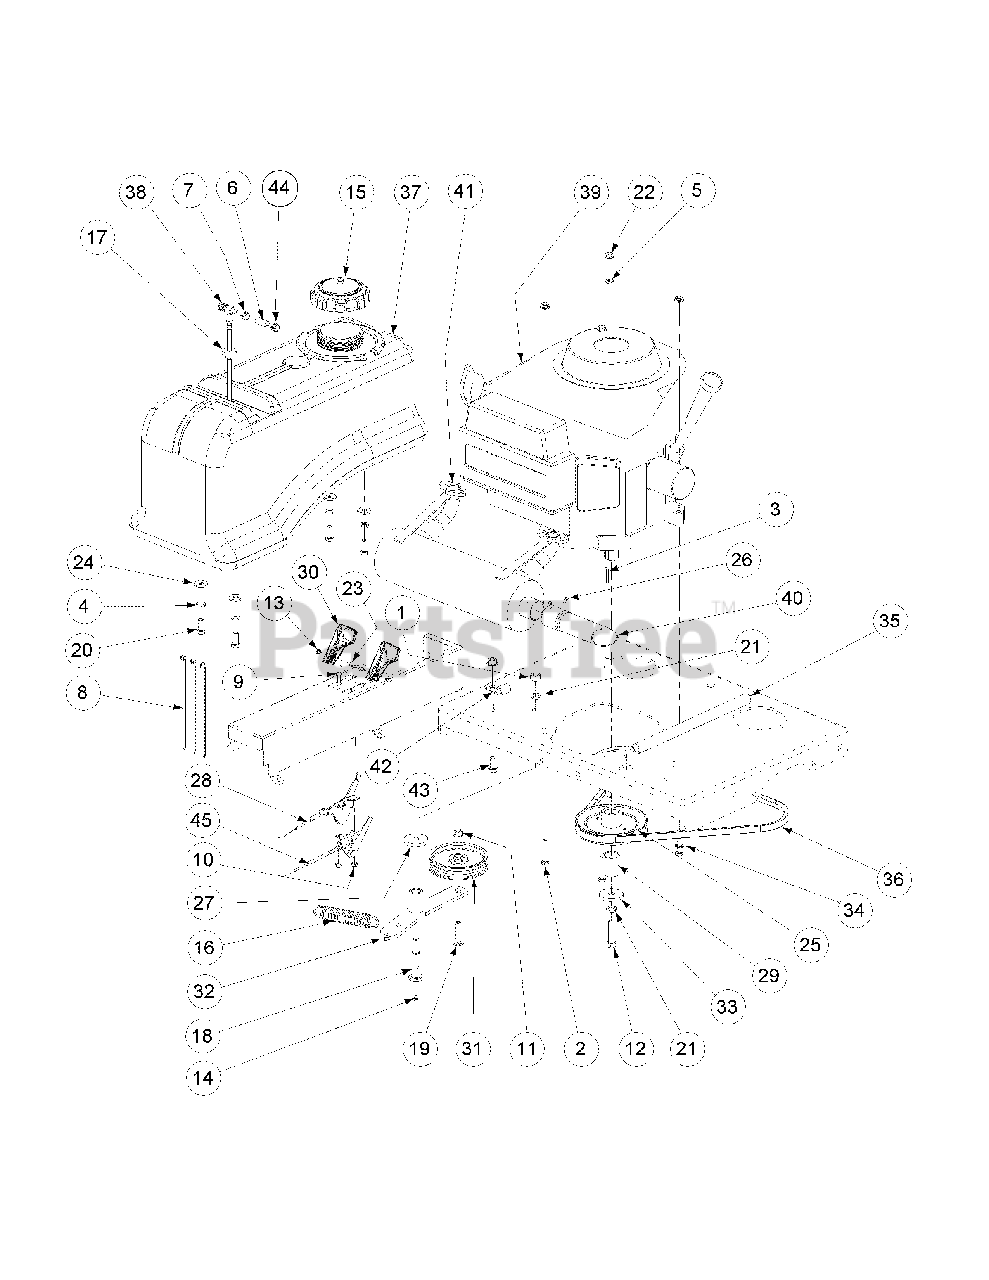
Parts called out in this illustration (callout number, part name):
1	Nut Hex, 7/16-14
2	HHCS, 5/16-18, 1-3/4
3	Key, 1/4 x 1/4 x 1.125
4	Lock Washer, 3/8
5	Flat Washer, 5/16
6	Hose, 1/4" Fuel Line
7	Clamp, Union
8	Cable Tie
9	Screw, Machine, 10-32 x 3/4
10	Nut, Lock, Nylon Insert, #10-32
11	Nut, Hex, Flange Lock, 3/8-16
12	Capscrew, 7/16-20 x 1.75
13	Nut, Washer, With Star, 8-32
14	Fitting, Grease, 1/4-28 x 3/16
15	Fuel Cap, 3.5
16	Spring, Extension, 1.0 OD x 5.0"
17	Fuel Tank Grommet
18	Shoulder Screw, 7/16-14
19	Bolt, Carriage, 3/8-16 x 1.75
20	Hex, Cap Screw, 3/8-16, .88
21	Washer, Lock, 7/16
22	Nut Lock, Hex Flange 5/16-18
23	Machine Screw, 8-32, .375
24	Flat Washer, .406 ID, 1.0 OD, .105
25	Pulley, Transmission Drive
26	Screw, 8-32 x 0.375
27	Washer, Flat, 7/16 ID x 1.75 OD
28	Cable, Control 39.0 Throttle
29	Spacer, 1.015 ID x 1.25 OD x 1.50
30	Knob, Throttle Control
31	Flat Pulley with Flanges
32	Engine Idler Arm Assembly Includes:
32	Bearing
33	Flat Washer, 7/16 ID x 1.75 OD
34	External Tooth Washer, 3/8
35	Oil Drain Extension Hose
36	Belt, Pump Drive
37	Fuel Tank
38	Fuel Fitting
39	Engine, 17HP Kawasaki
40	Tube, Exhaust Selxsys Muffler
41	Muffler Accessory Kawasaki
42	Clip, Heat Shield
43	HHCS: 3/8-16 x .750
44	Hose Clamp, SAE #4: 1/4-5/8, SS
45	Choke Control Cable
